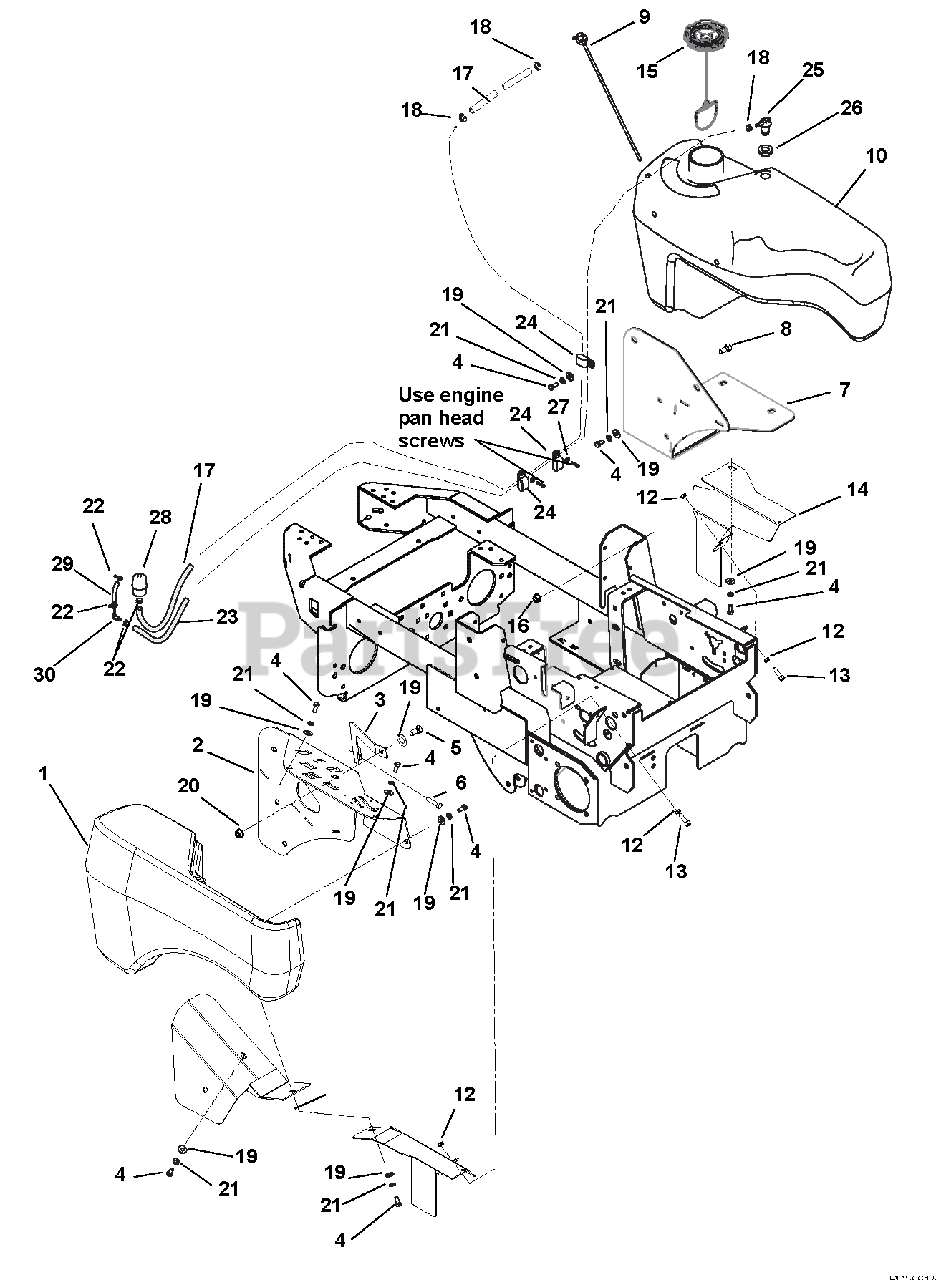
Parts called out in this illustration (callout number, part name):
1	FENDER, (RH) OUTFRONT
2	PANEL, CONTROL
3	STIFFENER, FENDER
4	@BLT-HEX .31-18X.75 GR5 YWZC
5	@BLT-HEX .38-16X.75 GR5 YWZC
6	@SCR-TAP .38-16X.50 HWH TR YWZ
7	BRKT, LH FUEL TANK (OUTFRONT)
8	@BLT-HEX .50-13X1.00 GR5 YWZC
9	ASSY,FUEL LINE W/90 DEG FTG
10	TANK, LH RAPID XZ FUEL
11	COVER, TIRE RH
12	NUT-HEX-JAM .375-16 YWZC
13	@BLT-HEX .38-16X1.25 GR5 YWZC
14	COVER, TIRE LH
15	CAP,3.50" VENT-IN RATCHET FUEL
16	@NUT-LK-NYL-FLG .50-13 YWZC
17	HOSE, .25 LOW-PERM BULK GAS
18	CLAMP, FUEL LINE
19	WSHR-FL-STL.38X.875X.083 YWZC
20	NUT-SPNLK-FLG .375-16 YWZC
21	@WSHR-LK .31X.078 REG YWZC
22	CLAMP-HOSE, SPRING .188
23	HOSE, .25 LOW-PERM BULK GAS
24	CLAMP, 5/8 INSUL TUBE YWZC
25	VALVE, COMBINATION
26	GROMMET, REMOTE VENT NITRILE
27	@WSHR-FL-STL.250X.56X.049 YWZC
28	FILTER, FUEL
29	HOSE, .188 LOW-PERM BULK GAS
30	FITTING-3/16X1/4 90DEGREE VAC
